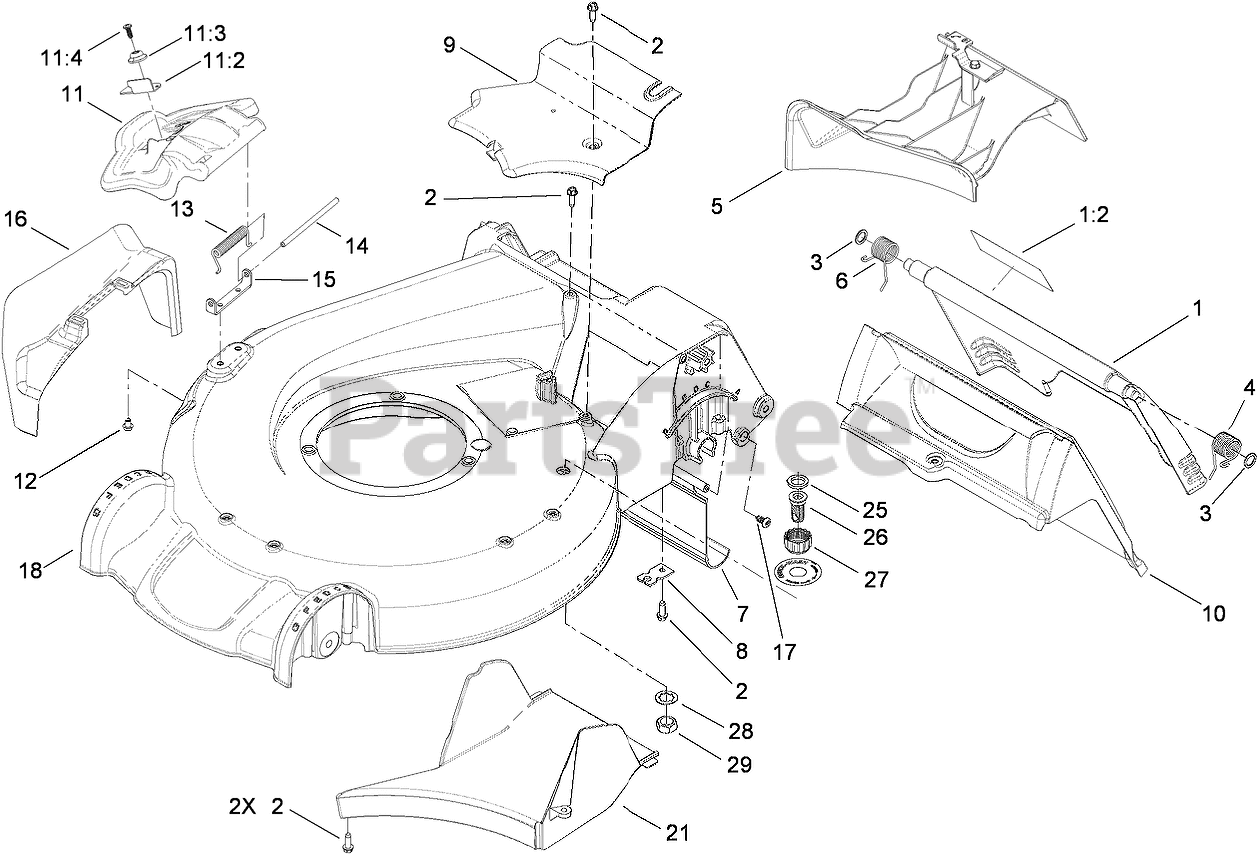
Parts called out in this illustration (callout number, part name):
1	REAR DOOR ASM
1:2	DECAL-WARNING
2	SCREW-HWHTF
3	WASHER-NYLON
4	SPRING-TORSION
5	MULCH PLUG ASM
6	SPRING-TORSION
7	SHIELD-TRAILING
8	BRACKET-CABLE, TRACTION
9	COVER-BELT
11	DISCHARGE DOOR ASM
11:2	LATCH-DOOR
11:3	CAP-DOOR
11:4	SCREW-PLASTITE
12	SCREW-HWH
13	SPRING-TORSION
14	ROD-COVER
15	BRACKET-COVER
16	CHUTE-DISCHARGE, SIDE
17	SCREW-PTH
18	HOUSING ASM
21	TUNNEL-DISCHARGE
25	WASHER-SEAL, WASHOUT PORT
26	PORT-WASHOUT
27	COUPLING-HOSE, WASHOUT PORT
28	WASHER-TOOTH, INTERNAL
29	NUT-JAM
